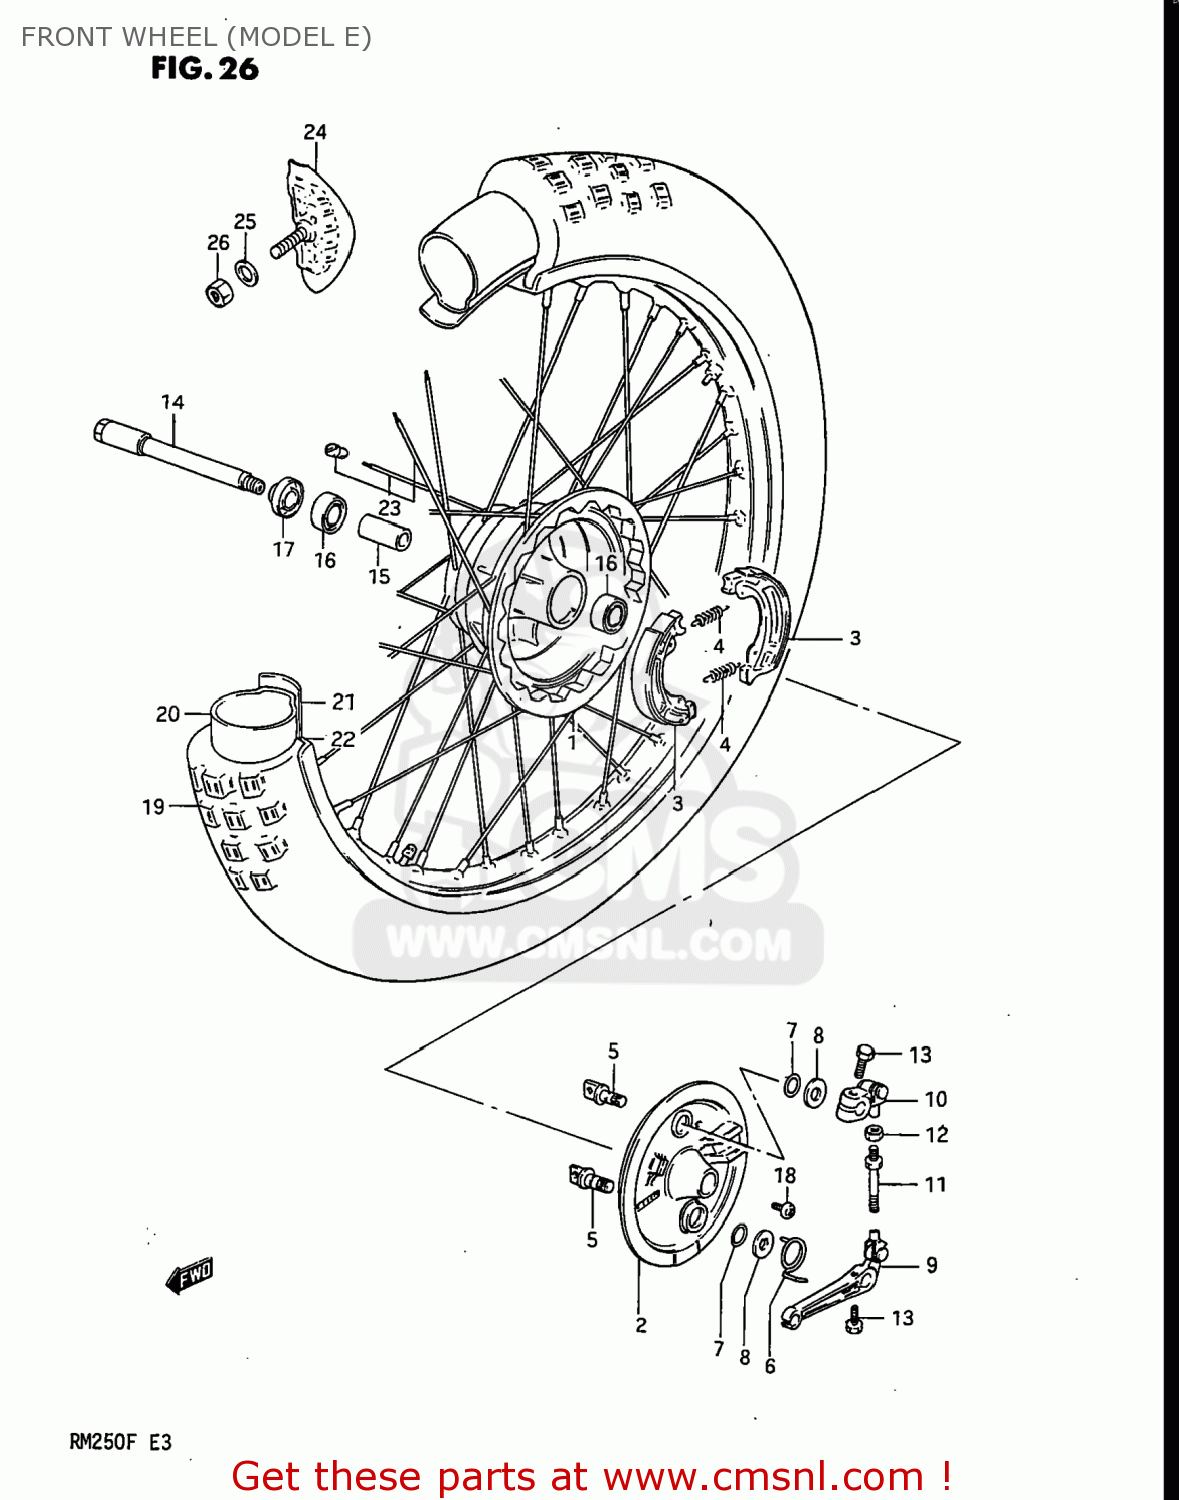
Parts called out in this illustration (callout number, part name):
1	DRUM,FRONT HUB
2	PANEL,FRONT HUB
3	SHOE,BRAKE (MCA)
4	SPRING
5	CAM,FRONT BRAKE
6	SPRING
7	O-RING (D:2 ID13.8)
8	WASHER (14.2X22X1)
9	SHOE SET,BRAKE
10	LEVER ASSY, BRAKE CAM, NO.2
11	ROD,BRAKE CAM LEVER CONNECTION
12	NUT 6MM
13	BOLT
14	AXLE,FRONT
15	SPACER,FRONT HUB BEARING
16	BALL BEARING 15X35X11
17	SPACER,FRONT AXLE,RIGHT
18	SCREW
19	TIRE,FRONT
20	TUBE
21	PROTECTOR,WHEEL,INNER
22	RIM,FRONT WHEEL (1.60X21)
23	SPOKE SET,FRONT
24	STOPPER,BEAD
25	WASHER
26	NUT 8MM
